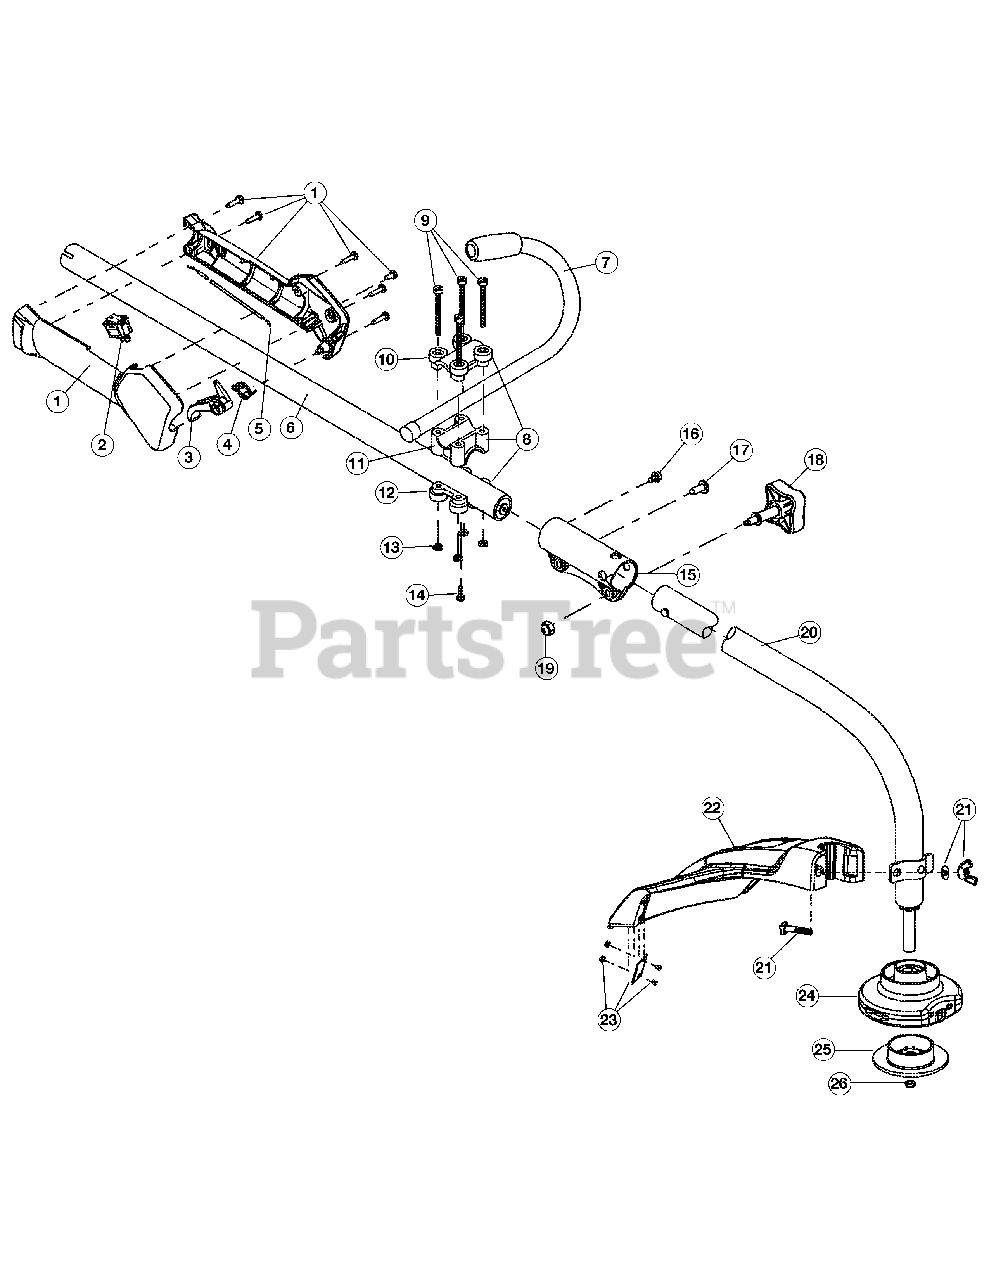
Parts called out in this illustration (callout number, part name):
1	Throttle Housing Assembly (includes 2-4)
3	Throttle Trigger
4	Throttle Trigger Spring
5	Throttle Cable
6	Upper Drive Shaft Housing Assembly
7	J-Handle Assembly
8	Handle Bracket Assembly (includes 9-14)
10	Upper Handle Clamp
11	Middle Handle Clamp
12	Lower Handle Clamp
14	Anti-Rotation Screw
15	Split Boom Coupler (includes 11-14)
18	Adjustment Knob
19	Knob Retaining Nut
20	Lower Drive Shaft Housing Assembly
21	Guard Mounting Hardware
22	Guard Assembly (includes 23)
23	Blade Assembly
24	Fixe Line Head Assembly (includes 25 & 26)
25	Glide Cap
26	Locknut
